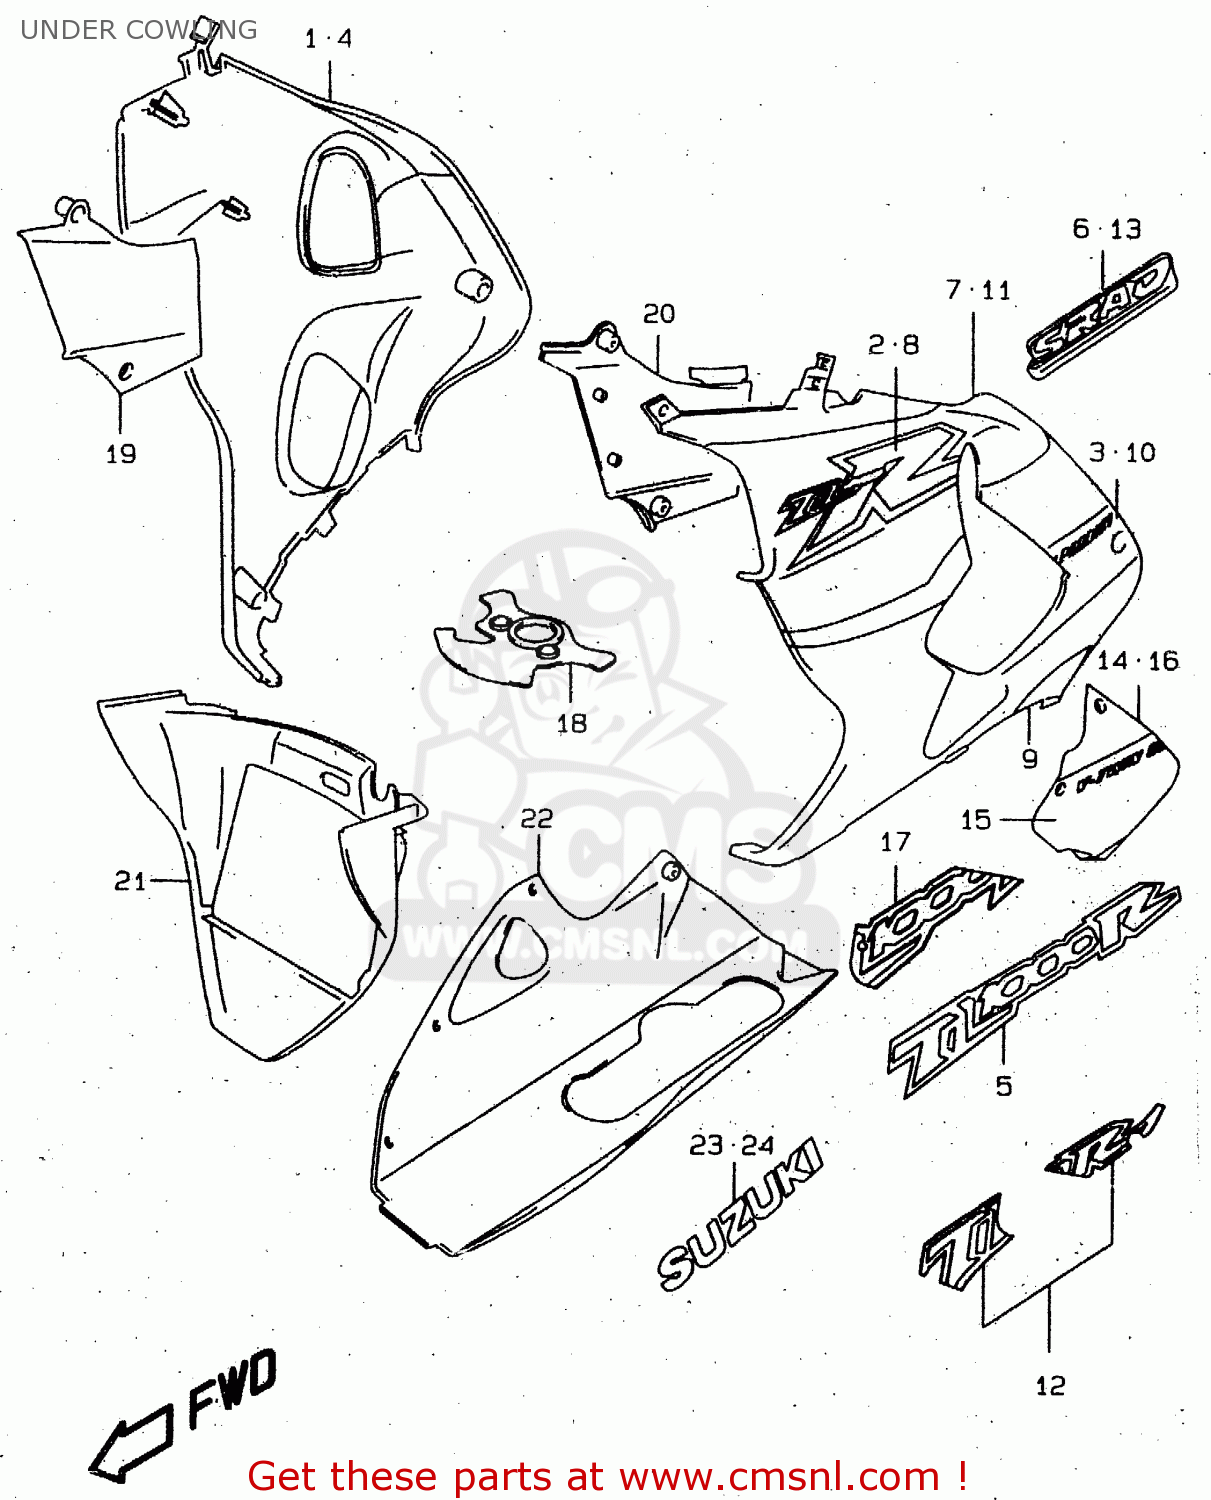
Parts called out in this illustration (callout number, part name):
1	COWLING ASSY,UNDER,R
2	EMBLEM,UNDER
3	TAPE,UNDER,RIGHT
4	COWLING ASSEMBLY,UNDER,RIGHT
5	EMBLEM,UNDER,1000R,R
6	EMBLEM,COWLING UNDER
7	COWLING ASSY,UNDER,L
8	EMBLEM,COWLING UNDER,L
9	TAPE,UNDER LWR,L
10	TAPE,UNDER UNDER,L
11	COWLING ASSEMBLY,UNDER,LEFT (R
12	TAPE,UNDER,UNDER (1000)
13	EMBLEM,COWLING UNDER
14	LID,UNDER,L(WHITE)
15	EMBLEM,LID,L
16	LID,UNDER,L(YELLOW)
17	EMBLEM,LID,L
18	COVER,LWR BRACKET
19	COWLING,UNDER INNER,R
20	COWLING,UNDER INNER,L
21	COWLING,UNDER CTR
22	COWLING ASSY,UNDER RR
23	EMBLEM,UNDER COWL RR,R
24	EMBLEM,UNDER RR
